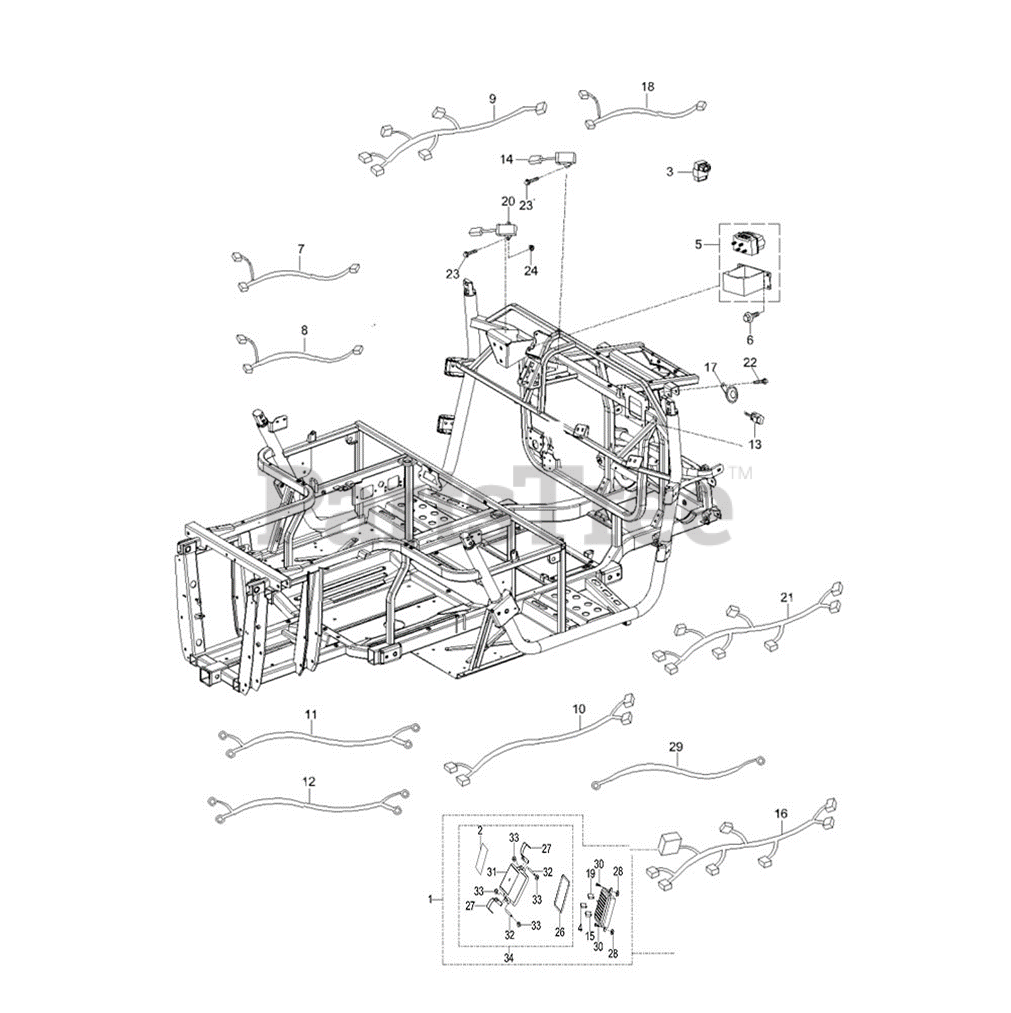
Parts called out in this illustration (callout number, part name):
1	Fuse Box
2	FUSE BOX LABEL
4	SUPPLEMENTARY RELAY
5	WINCH RELAY
6	HEXAGON FLANGE BOLT M6X16
7	SWITCH HARNESS
8	CABLE-SWITCH KIT 2
9	GROUND HARNESS
10	VOLTAGE REGULATOR HARNESS
11	CABLE-WINCH RELAY OUTLET
12	WINCH CABLE
13	RADIATOR FAN RELAY
15	CUTOUT RELAY
16	MAIN HARNESS
17	HORN ASSEMBLY
18	BATTERY HARNESS
19	FLASHER RELAY
20	SPEED LIMITER 750 (2018)
20	SPEED LIMITER 550 (2018)
21	HARNESS-750 EFI
22	CROSS PLATE HEAD SCREW M6X12
23	HEXAGON FLANGE BOLT M6X20
24	LOCK NUT M6
25	HEXAGON FLANGE BOLT M6X20
26	FUSE BOX GASKET
27	FUSE BOX CLAMP
28	HEX FLANG NUT M6
29	GROUND HARNESS
30	SOCKET HEX HEAD SCREW M6X20
31	FUSE BOX COVER
34	FUSE BOX COVER W/ GASKET
